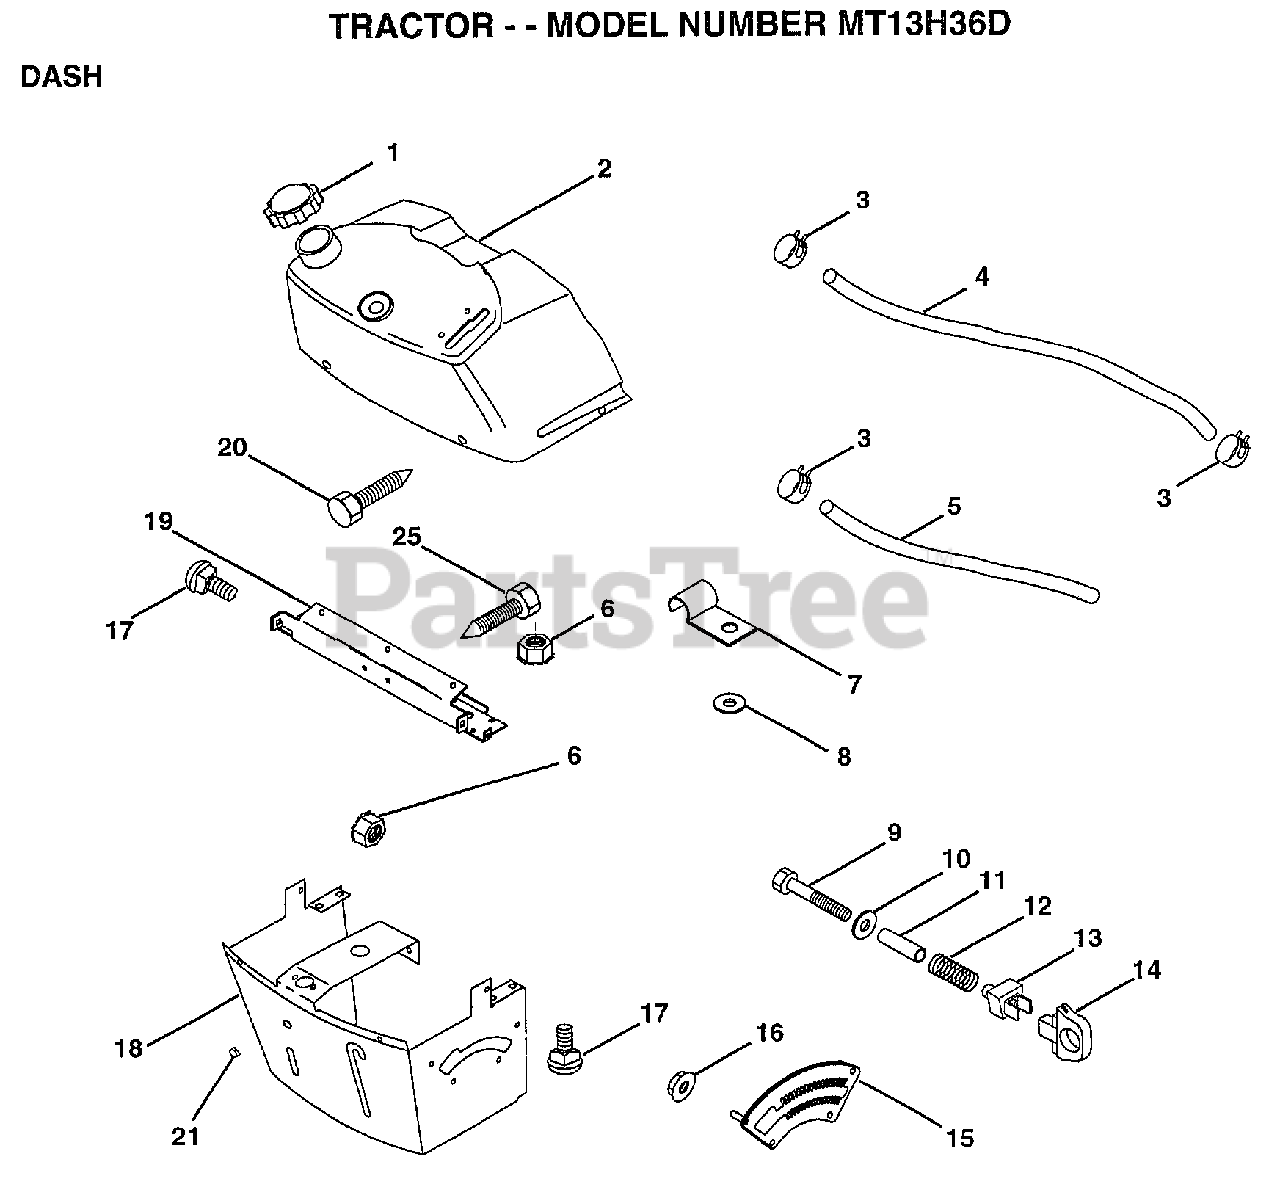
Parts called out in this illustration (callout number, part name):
1	CAP BLK FUEL LR
2	TANK.ASM.DASH.LR
3	HOSE CLAMP
5	FUEL LINE T
6	NUT HXKEP 1/4X20
7	CLIP T
8	WASHER PM
9	BOLT
11	SPACER SPLIT
12	SPRING M
13	"KNOB,HGT RETAINER"
14	KNOB
15	ADJUSTER QUAD
16	NUT
17	BOLT
18	SUPT ASSY DASH
19	CROSS BRACE
20	SCREW.1/4-20X1/2
21	PLUG DOME
25	SCREW LT
